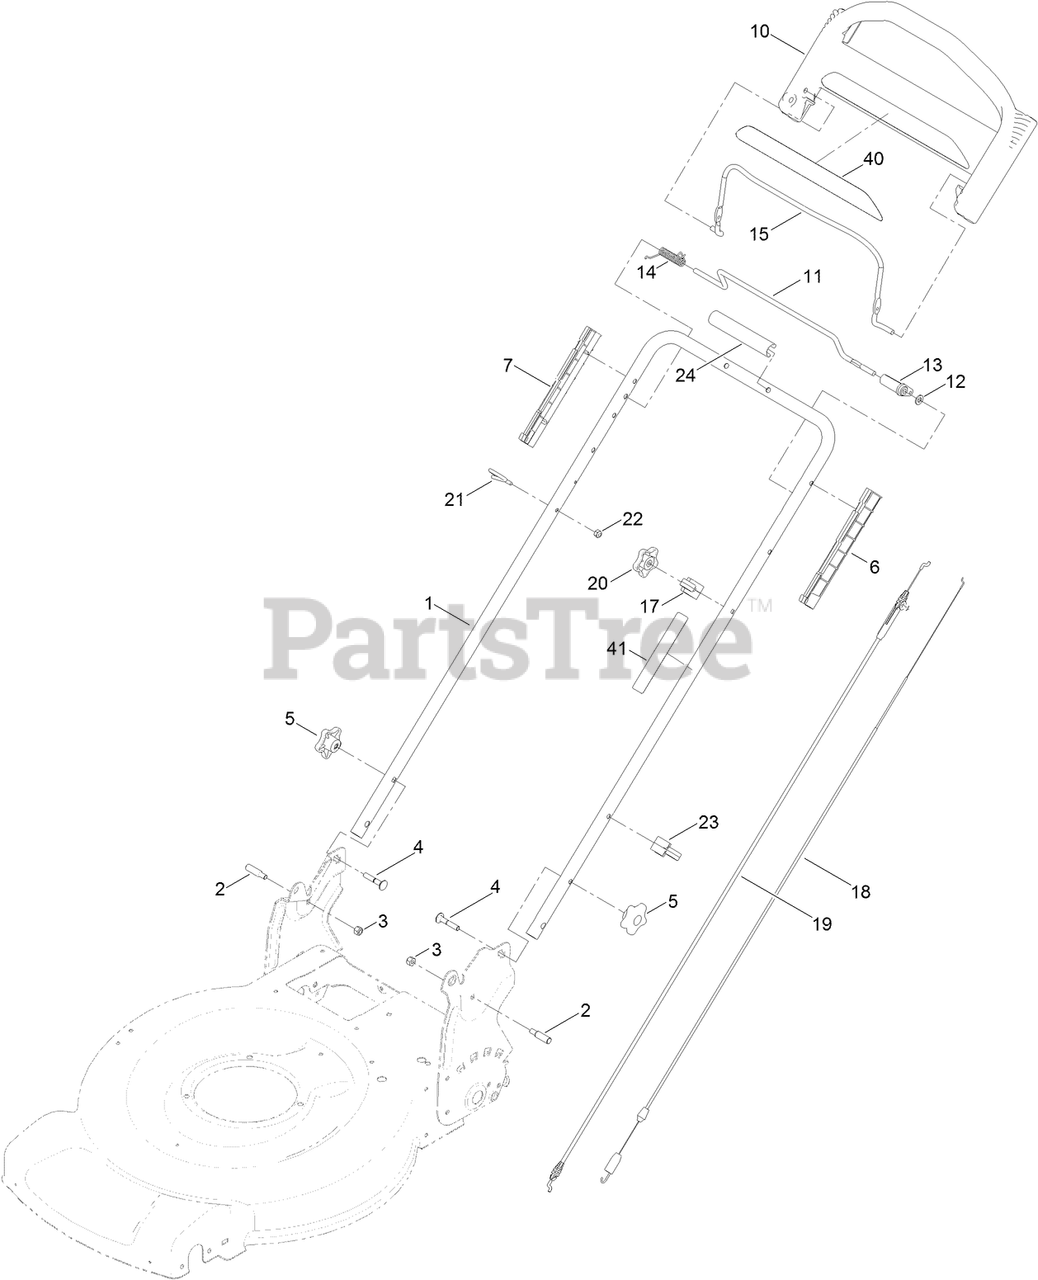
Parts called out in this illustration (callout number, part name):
2	BOLT-SHOULDER
3	NUT-LOCK, NI
4	SCREW-CARR
5	KNOB-HANDLE
6	GUIDE-LH
7	GUIDE-RH
10	HANDLE-CONTROL
12	WASHER-PLAIN
13	LEVER-TRACTION
15	BAIL-BRAKE
17	ANCHOR-CABLE
18	CABLE-TRACTION
19	CABLE-BRAKE
20	KNOB-HANDLE, LOCKING
21	GUIDE-ROPE
22	NUT-LOCK, NI
23	GUIDE-CABLE
24	HANDLE-COVER
41	DECAL-TRACTION, ADJUST
